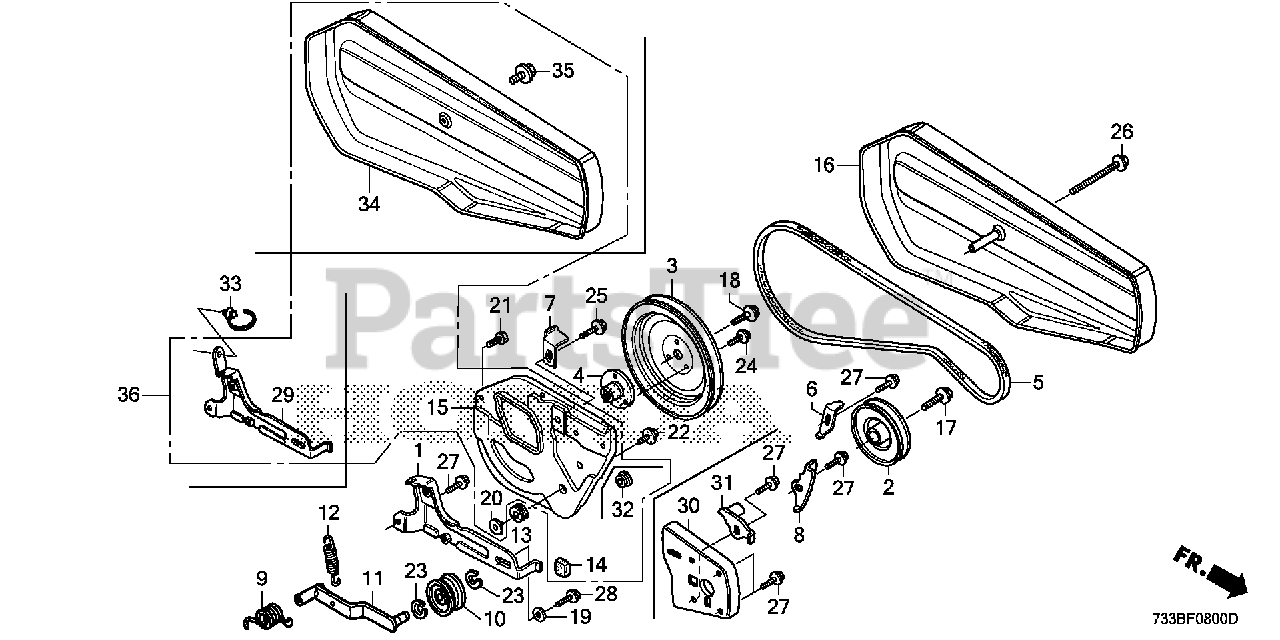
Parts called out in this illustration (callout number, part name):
1	STAY, ENGINE
2	PULLEY, DRIVE (80MM)
3	PULLEY, DRIVEN (141MM)
4	BOSS, DRIVEN PULLEY
5	V-BELT (37.5)
6	STOPPER, BELT (UPPER)
7	STOPPER C, BELT
8	STOPPER, BELT (LOWER)
9	SPRING, TENSION ARM RETURN
10	ROLLER (TENSION)
11	ARM, TENSION
12	SPRING, BELT TENSIONER
13	GROMMET, WIRE HARNESS
14	HOLDER, FUSE STAY (NOT AVAILABLE)
15	STAY, BELT COVER
16	COVER, BELT *R280* (POWER RED)
17	BOLT, FLANGE (8X22)
18	BOLT, FLANGE (8X18)
19	WASHER (8MM)
20	WASHER, NUMBER BRACKET MOUNTING
21	BOLT, HEX. (6X8)
22	BOLT-WASHER (6X16)
23	CIRCLIP (OUTER) (10MM)
24	BOLT, FLANGE (6X10)
25	BOLT, FLANGE (6X12) Use up to Engine SN 1543277.
26	BOLT, FLANGE (6X50)
27	BOLT, FLANGE (8X16) Use from Engine SN 1000016.
28	BOLT, FLANGE (8X20) Use up to Engine SN 1609606.
